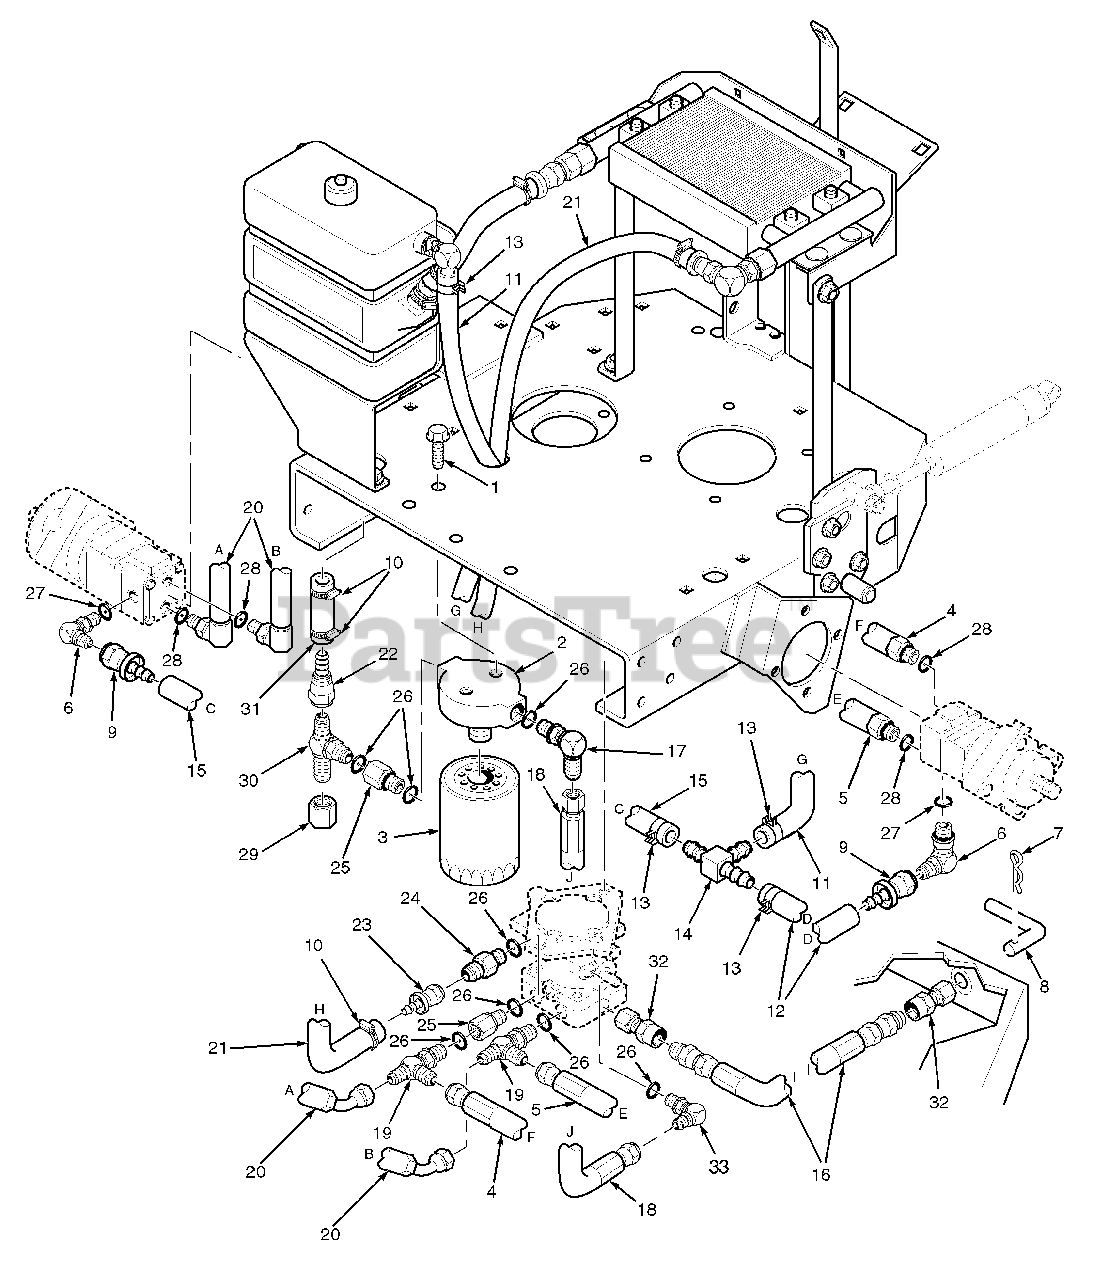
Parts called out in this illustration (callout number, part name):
1	Capscrew, 1/4-20 x1/2 Serr. Fl. Hex Head
2	Filter Head
3	Filter, Spin-On Lube
4	Hose Assembly
5	Hose Assembly
6	Elbow, 90 Degrees
7	Hairpin Cotter
8	Lever, Dump Valve
9	Connector, Flare Swivel with Hose Barb
10	Hose Clamp
11	Hose, 1/4 Pushlock
12	Hose, 1/4 Pushlock
13	Hose Clamp
14	Tee Union, Pushlock Hose
15	Hose, 1/4 Pushlock
16	Hose, Dump Valve
17	Elbow, 90 Deg.
18	Inlet Hose, 3/4" ID
19	Tee, 1/2" Run
20	Motor Hose
21	Hose, Pump To Oil Cooler
22	Coupling, Flare Swivel
23	Coupling, Flare Swivel With Barb
24	Tube Union
25	O-Ring Bushing
26	O-Ring
27	O-Ring
28	O-Ring
30	Tee, JIC to O-Ring
31	Hose
32	Compression Fitting
33	Elbow, 90 Deg.
